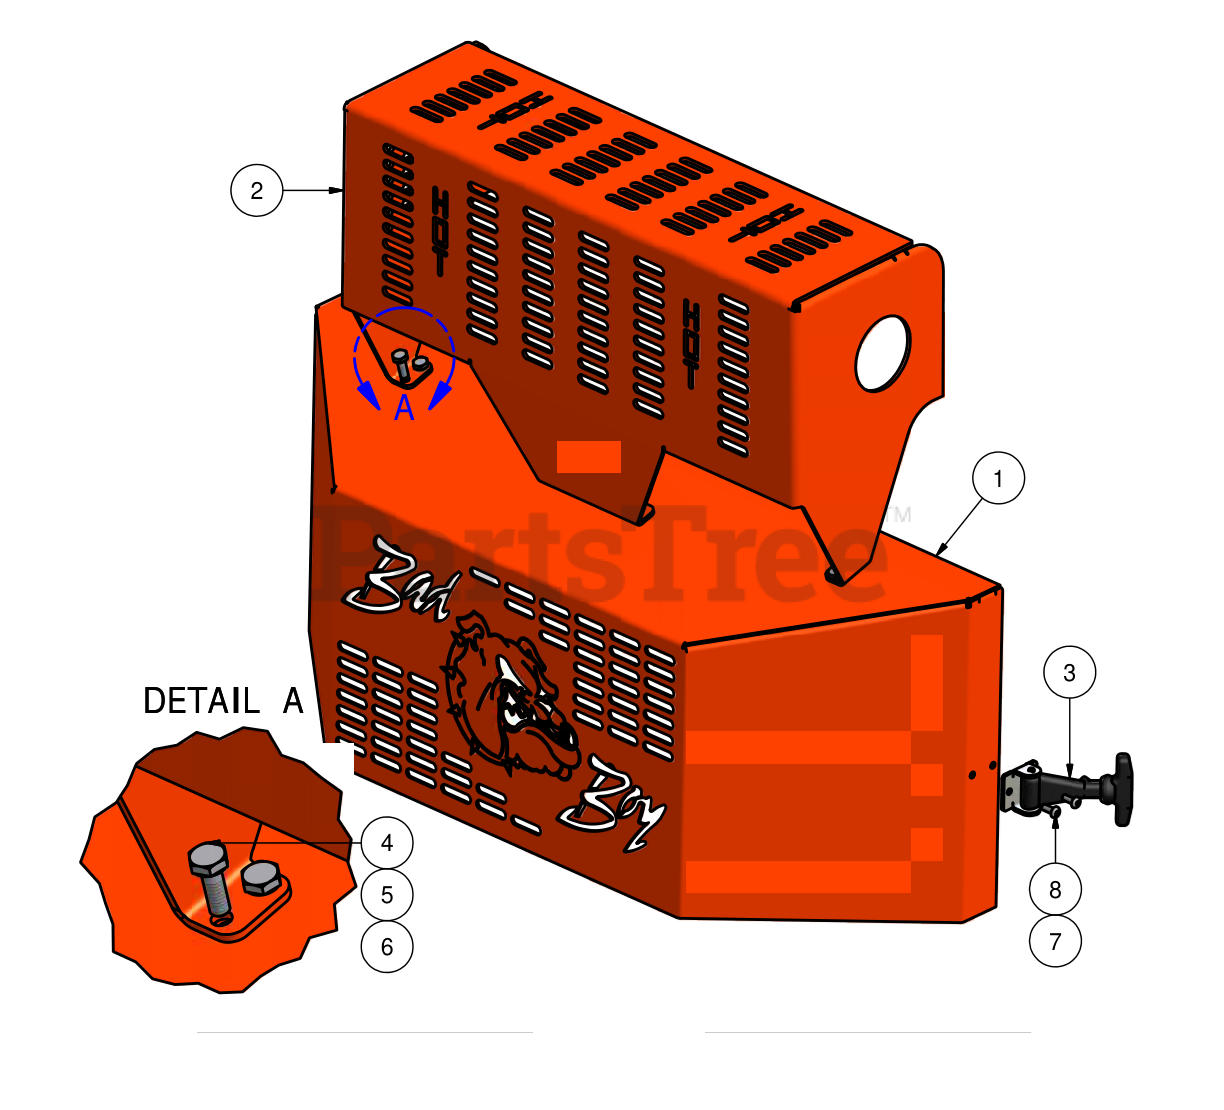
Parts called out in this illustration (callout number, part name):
1	Pump Cover (35 hp)
2	Muffler Guard (35hp)
3	Cover Latch
4	1/4" x 3/4" SS Buttonhead Bolt
5	1/4" Lock Washer
7	1024 Nylock Nut
8	1024 x 3/4" Buttonhead Bolt
